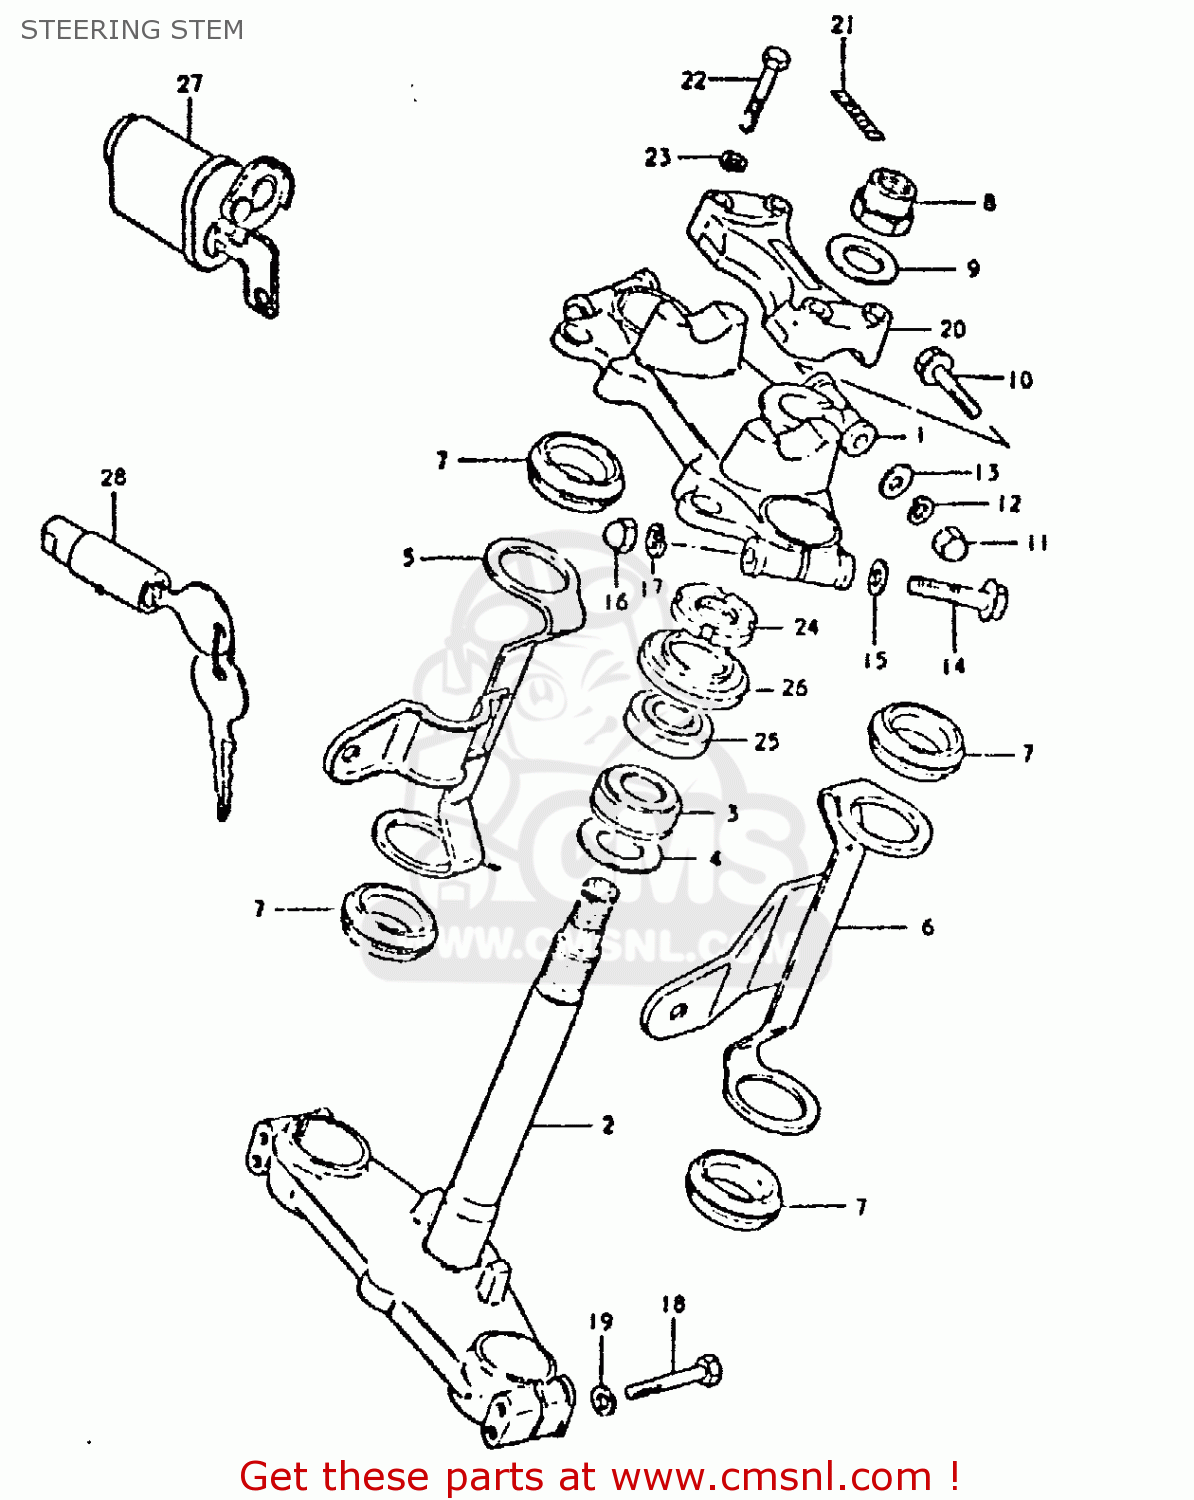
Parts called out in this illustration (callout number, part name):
1	HEAD,STEERING STEM
2	STEM,STEERING
3	BEARING
4	WASHER,THRUST
5	BRACKET,HEADLAMP,RIGHT
6	BRACKET,HEADLAMP,LEFT
7	CUSHION,HEADLAMP BRACKET
8	NUT,FR FORK UPR BRACKET
9	WASHER
10	BOLT
11	NUT,M8X1.25X12
12	LOCK WASHER
13	WASHER
14	BOLT 10X55
15	WASHER
16	NUT
17	LOCK WASHER
18	BOLT 8X45
19	WASHER,LOCK,8.
20	HOLDER,HANDLEBAR
21	EMBLEM,HANDLE CLAMP
22	BOLT
23	LOCK WASHER
24	NUT,STEERING STEM(25X44X10)
25	TAPER,ROLLER BEARING
26	DUST SEAL,STEERING,UPPER
